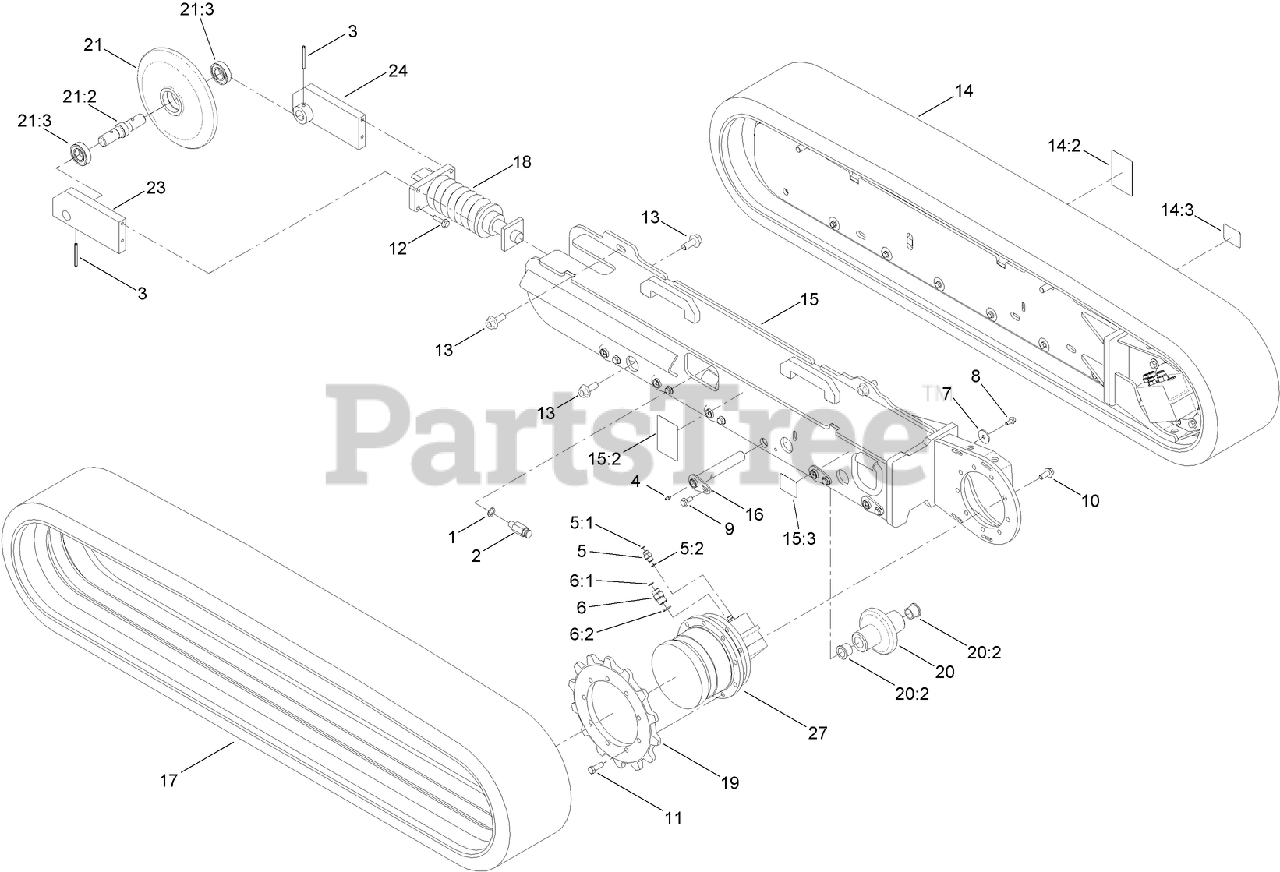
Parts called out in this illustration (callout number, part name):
1	SEAL-O RING
2	VALVE-GREASE
3	PIN-SPRING
4	FITTING-GREASE
5	FITTING-STRAIGHT
5:1	O-RING
5:2	O-RING
6	FITTING-STRAIGHT
6:1	O-RING
6:2	O-RING
7	WASHER
8	SCREW-HHF
9	SCREW-HHF
10	SCREW-HHF
11	SCREW-HH
12	SCREW-HHF
13	SCREW-HHF
14	LH TRACK ASM
14:2	DECAL-WARNING, THROWN OBJECTS
14:3	DECAL-TIE DOWN
15	RH TRACK ASM
15:2	DECAL-WARNING, THROWN OBJECTS
15:3	DECAL-TIE DOWN
16	PIN-FLAG
17	TRACK-RUBBER
18	TENSIONER-TRACK, SPRING/GREASE
19	SPROCKET-DRIVE, TRACK
20	IDLER ASM
20:2	BEARING-PLAIN, FLANGED
21	IDLER ASM
21:2	PIN-MOUNT, IDLER
21:3	BEARING-BALL
23	BRACKET-IDLER, RIGHT
24	BRACKET-IDLER, LEFT
27	PLANETARY GEARBOX ASM
